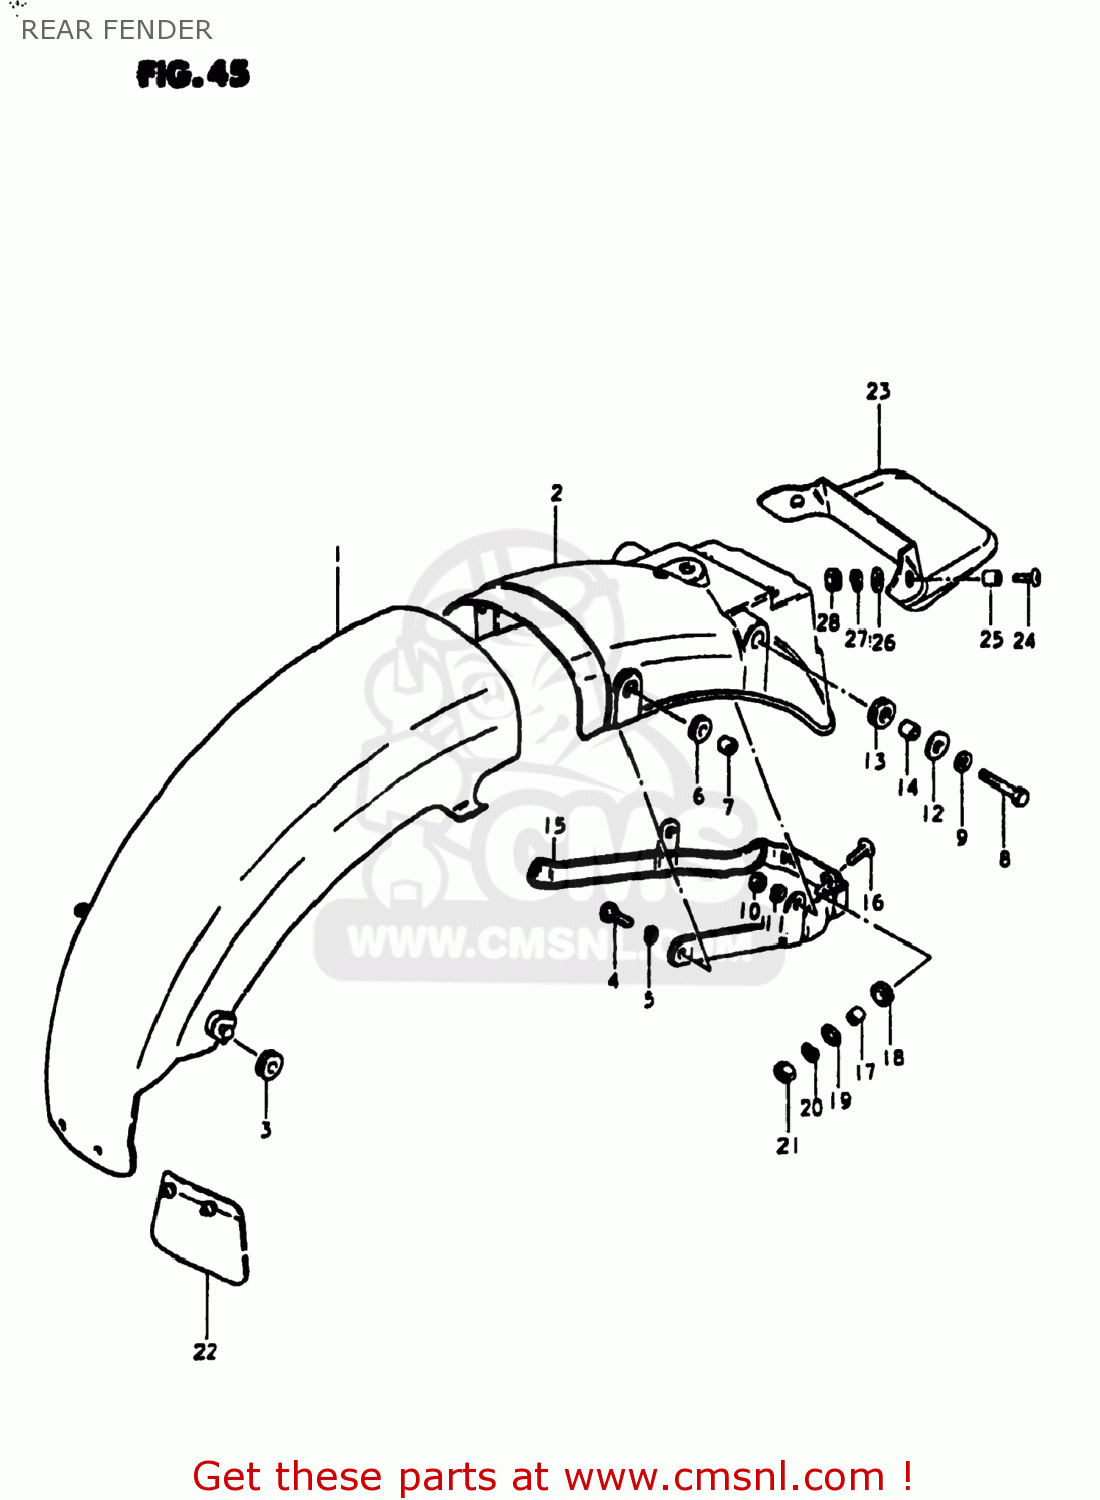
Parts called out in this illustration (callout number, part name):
1	FENDER,REAR
2	BODY,RR FENDER RR
3	CUSHION
4	BOLT
5	LOCK WASHER
6	CUSHION
7	SPACER(6.1X9X7.5)
8	BOLT
9	WASHER
10	NUT
11	LOCK WASHER
12	WASHER(8.5X26X1.2)
13	CUSHION
14	SPACER (8.2X12X7.5)
15	REINFORCEMENT,REAR FENDER
16	SCREW
17	SPACER (6.1X9X9)
18	CUSHION
19	WASHER(6,5X22X1.6)
20	LOCK WASHER
21	NUT
22	GUIDE,RR FENDER MUD
23	EXTENSION,REAR FENDER
24	SCREW (6X15)
25	SPACER(6.2X8.3X5.7)
26	WASHER(6.5X18X1)
27	LOCK WASHER
28	NUT
